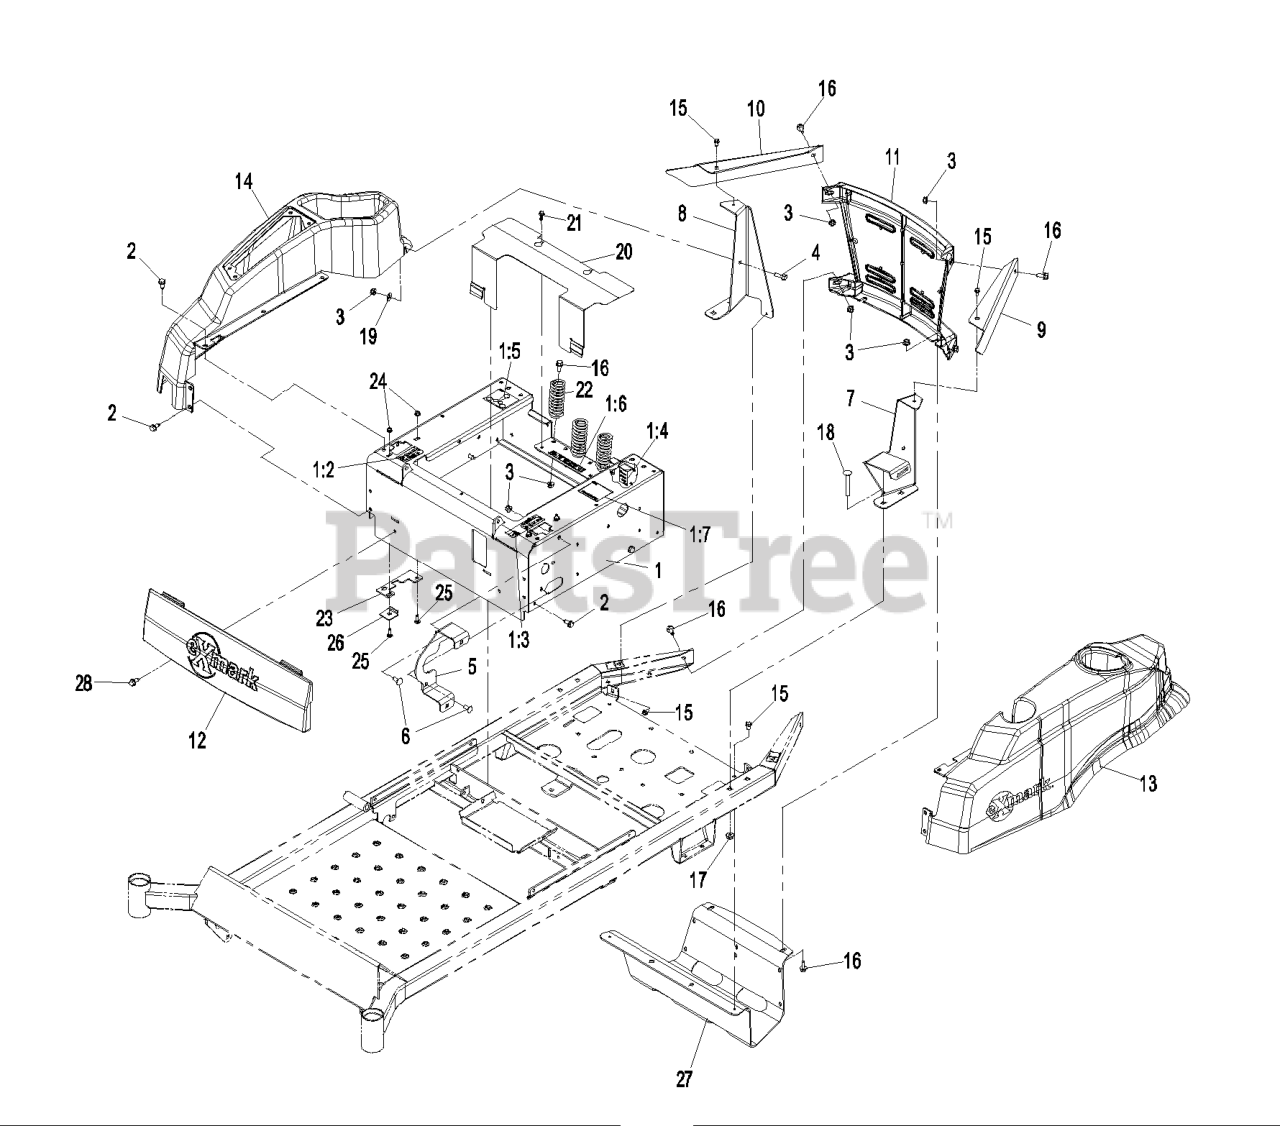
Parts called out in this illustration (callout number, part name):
1	ASM,SEAT BOX SERVICE
1:2	DECAL-MOTION CONTROL
1:3	DECAL-CONTROL BRAKE
1:4	DECAL-FUSE BLOCK
1:5	DECAL-ROUTING, BELT
1:6	DECAL-DANGER
1:7	DECAL,ENGINE RPM
2	Screw-HWH 5/16-18 X 3/4 Tf
3	NUT-HF, NI
4	SCREW-HH
5	BRACKET-TANK MOUNT
6	SCREW-CARR
7	BRACKET,REAR TANK LH
9	GUARD,ENGINE LH
10	GUARD,ENGINE RH
11	CASTING,REAR EXMARK
12	PANEL,FRONT EXMARK
13	FENDER,EXMARK LH
14	FENDER,EXMARK RH
15	SCREW-HWH
16	SCREW-HHF
17	NUT-HF, NI
18	SCREW-CARR
19	WASHER-FLAT
20	COVER-HYDRO FAN
21	SCREW-HHF
22	SPRING-COMPRESSION
23	PLATE,NEUTRAL
25	BOLT-CARR
26	PLATE,TRACKING
27	GUARD-MUFFLER
28	SCREW
